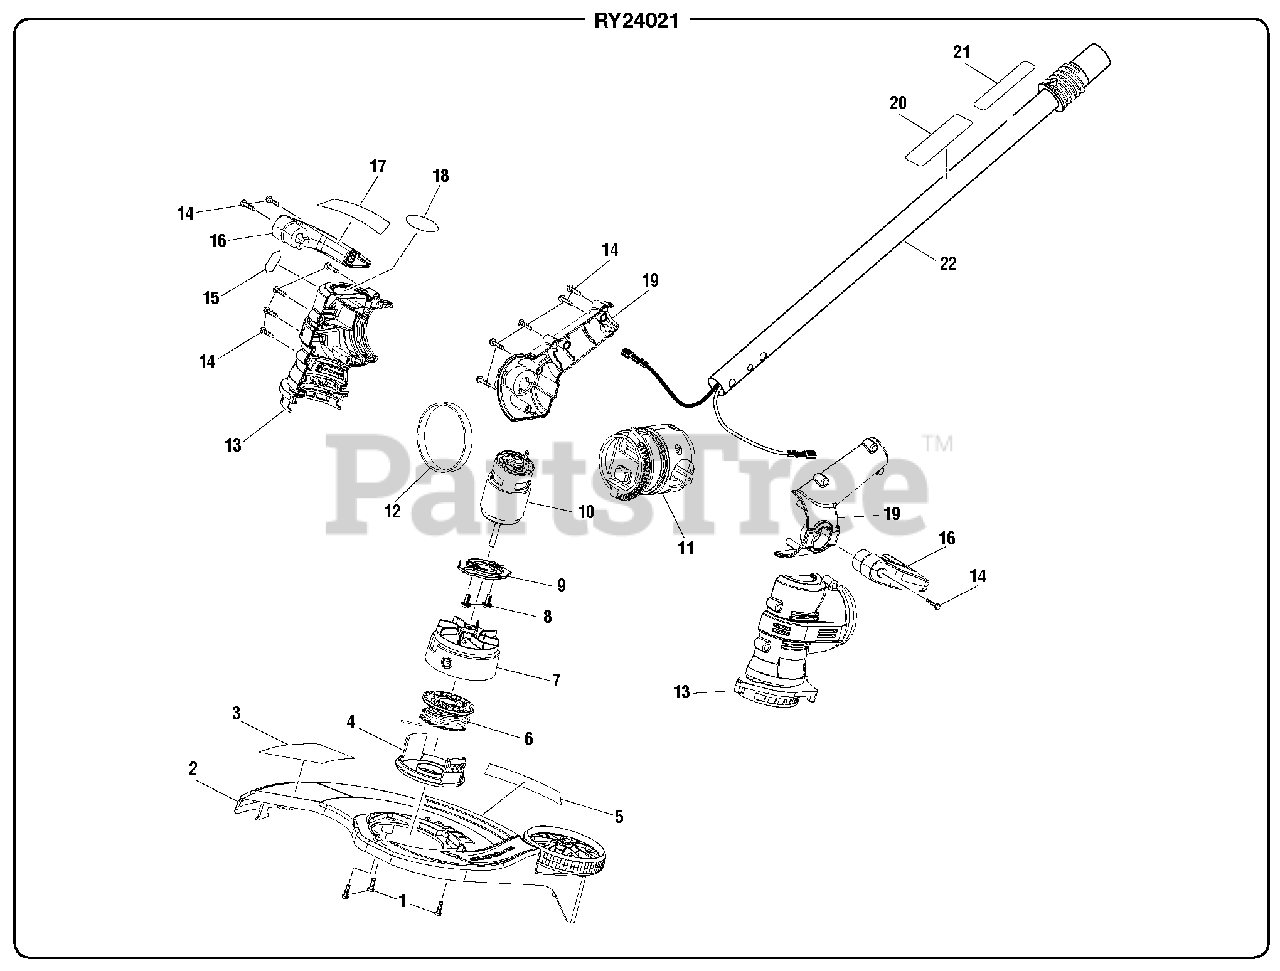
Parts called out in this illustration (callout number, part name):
1	Screw (M4 x 12 mm, Pan Hd.)
2	Grass Deflector Assembly
3	Adjustable Cutting Width Label
4	Spool Cap (AC14HC)
5	No Bump Label
6	Spool w/Line (AC14RSL)
7	String Head Assembly
8	Screw w/Lock Washer (M5 x 8 mm, Pan Hd.)
9	Motor Mounting Plate
10	Motor (24 Volt)
11	Pivot Assembly
12	Glamour Ring
13	Motor Housing Assembly
14	Screw (M4 x 14 mm, T15 Torx Pan Hd.)
15	Rotate Label
16	Foot Pedal Assembly
17	Step For Edging Label
18	Lithium 24V Motor Housing Label
19	Lower Housing Assembly
20	Data/Warning Icon Label
21	Ryobi Connexion Label
22	Lower Boom Assembly
